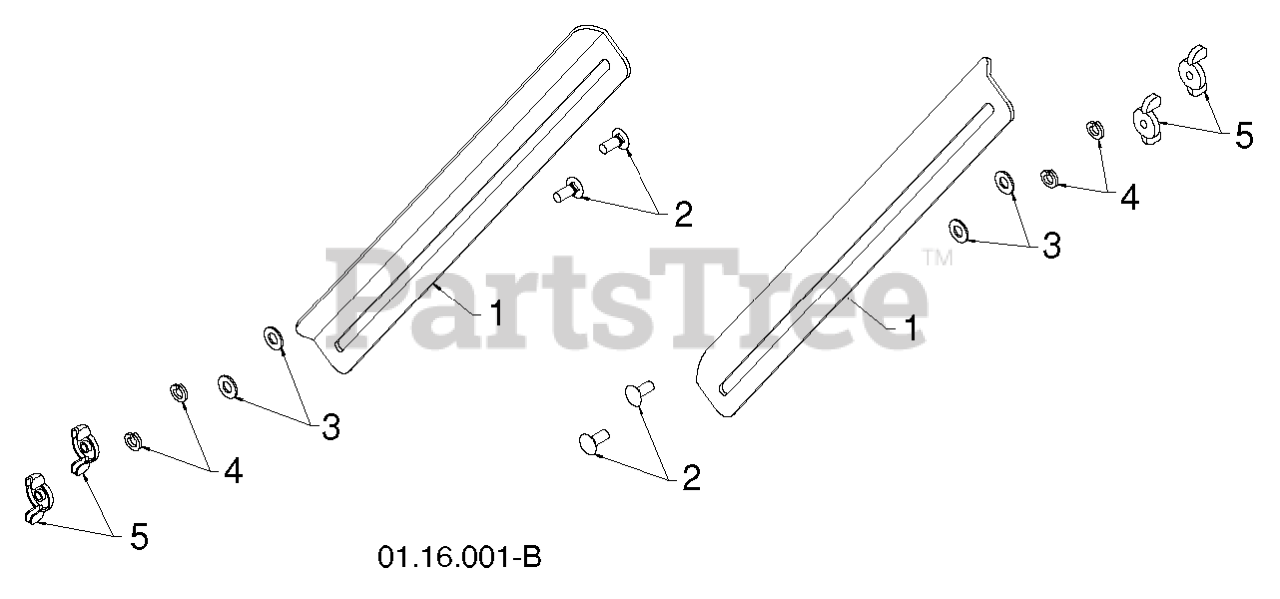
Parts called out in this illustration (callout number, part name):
1	DRIFT CUTTER BAR
2	BOLT
3	WASHER, NYLON FRICTION
4	WASHER.LOCK.HVY.HLCL.SPR.5/16
5	NUT WING PM
